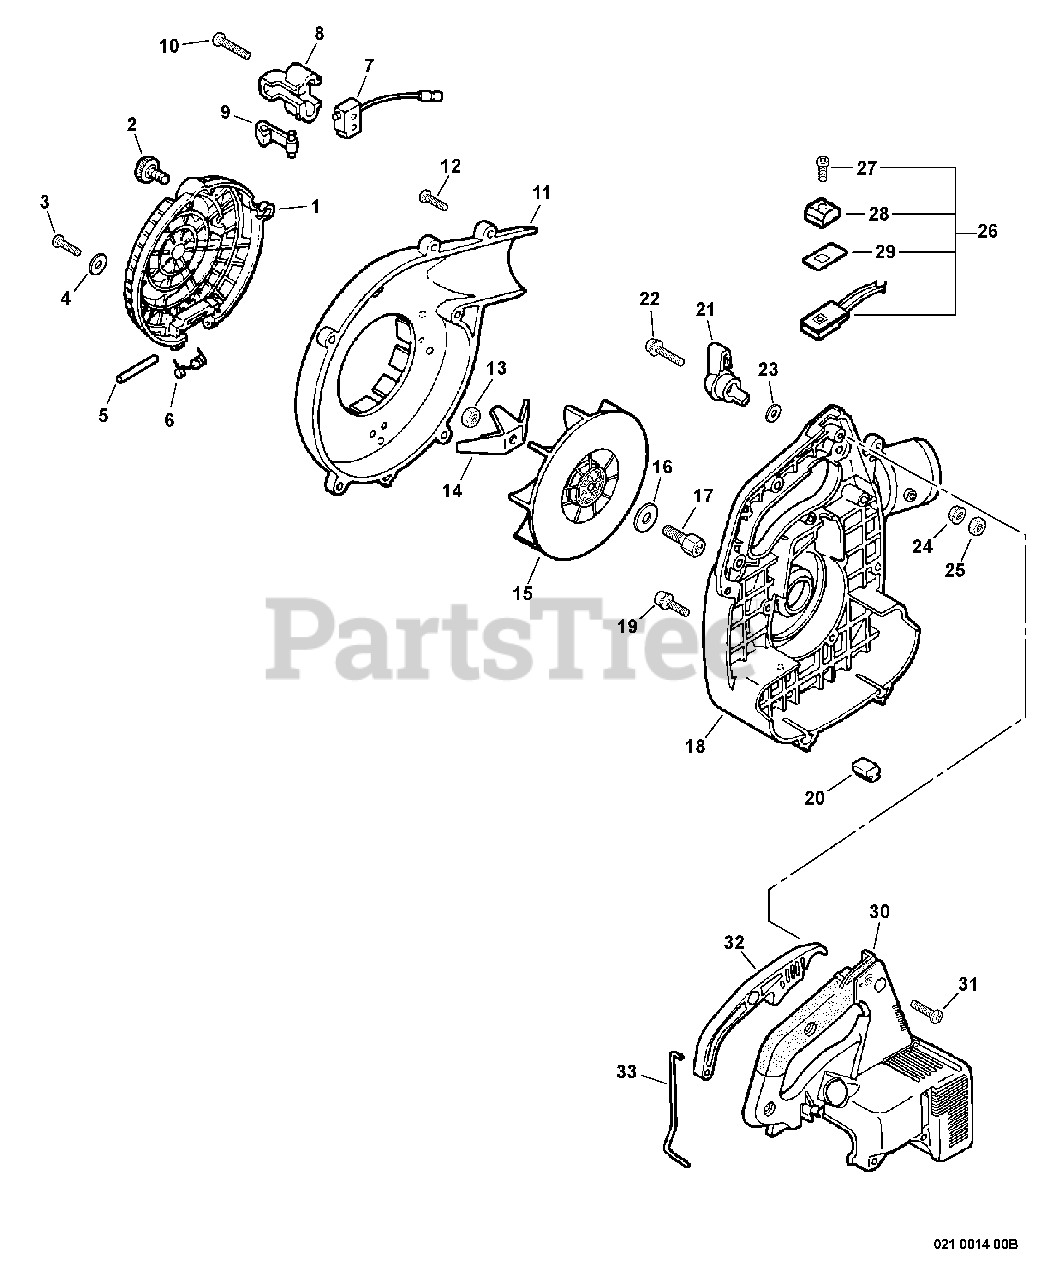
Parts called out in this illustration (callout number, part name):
1	GUARD, DEBRIS
2	THUMBSCREW
3	SCREW - 5X14
4	WASHER - 5
7	IGNITION SWITCH ASSY
8	BRACKET, SWITCH
9	ACTUATOR
10	SCREW - 4X22
11	COVER, FAN - LEFT
12	SCREW - 5X20 -- TAPPING
14	BLADE, SHREDDER
16	WASHER - 8
17	HUB, FAN
18	COVER, FAN - RIGHT
19	SCREW - 4X22
21	LEVER, THROTTLE - BLACK
22	SCREW - 5X25
23	WASHER - 5
24	NUT - 5 -- FLANGE
26	IGNITION SWITCH ASSY
27	SCREW - 3X10
28	KNOB, SWITCH
29	COVER, SWITCH - STOP
30	COVER, ENGINE
31	SCREW - 5X20 -- TAPPING
32	TRIGGER, THROTTLE - BLACK
33	ROD, THROTTLE
